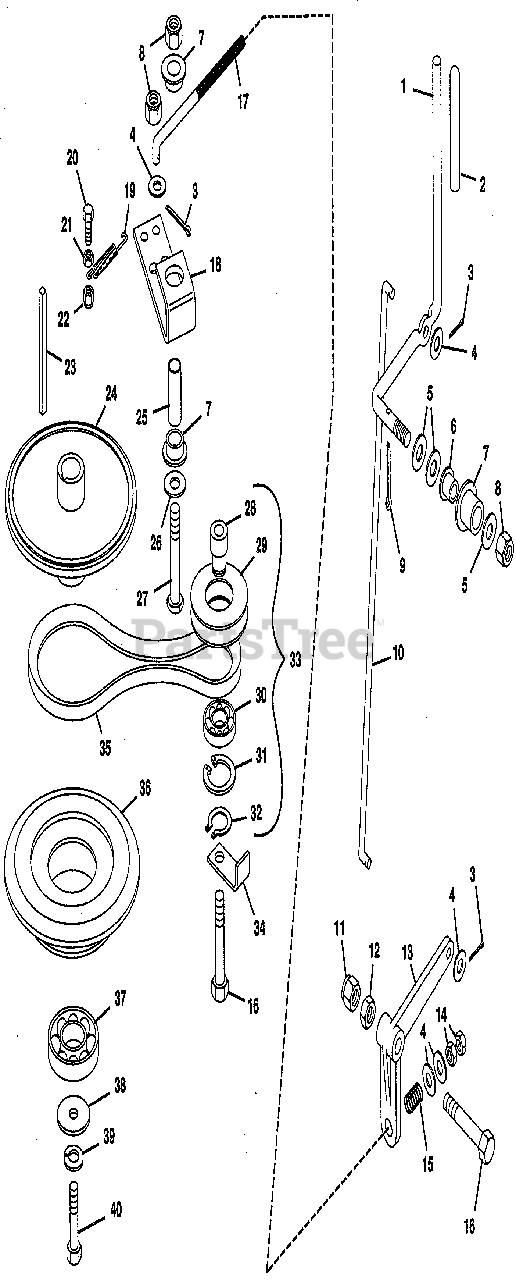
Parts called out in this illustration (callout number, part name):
1	LEVER, PTO ACTUATING
2	GRIP, PTO LEVER
3	PIN, COTTER .09 X .75
4	WASHER, FLAT .406 X .812 X .065
5	WASHER, FLAT .531 X 1.250 X .100
6	BUSH., FLG. .515 X 1.00 X .745 NY.
7	BUSH., FLG. .764 X 1.47 X .560 NY.
8	NUT, LOCK 1/2-13
9	PIN, COTTER .187 X 1.25
10	ROD, PTO CONTROL
11	NUT, LOCK 1/2-13
12	NUT, JAM 1/2-13
13	LEVER, PTO CLUTCH
14	NUT, HEX 3/8-16
15	SPRING, COMP. 1 X .78 X 388
16	BOLT, HEX 1/2-13 X 2.50
17	ROD, PTO CLUTCH ACTUATING
18	ARM, IDLER PIVOT
19	SPRING, PTO RETURN
20	BOLT, HEX 5/16-18 X 1.00
21	NUT, HEX 5/16-18
22	NUT, LOCK 5/16-18
23	KEY, SQUARE .250 X 3.60
24	HUB, PTO CLUTCH
25	BUSH., ST. .560 X .745 X 2.04 STL.
26	WASHER, FLAT .531 X .787 X 1.41 STL.
27	BOLT, HEX 1/2-13 X 2.75 SPECIAL
28	BUSH., FLG. .515 X 787 X 1.41 STL
29	SHEAVE, IDLER
30	BEARING, BALL
31	RING, RETAINING
32	RING, RETAINING
33	ASSEMBLY, IDLER SHEAVE
34	GUIDE, BELT
35	V-BELT, PTO CLUTCH
36	SHEAVE, MOWER CLUTCH
37	BEARING, BALL 1.574 X 3.149 X .708
38	WASHER, SPECIAL
39	WASHER, LOCK 7/16 REG.
40	BOLT, HEX 7/16-20 X 2.50
40	BOLT, HEX 10MM X 1.50
